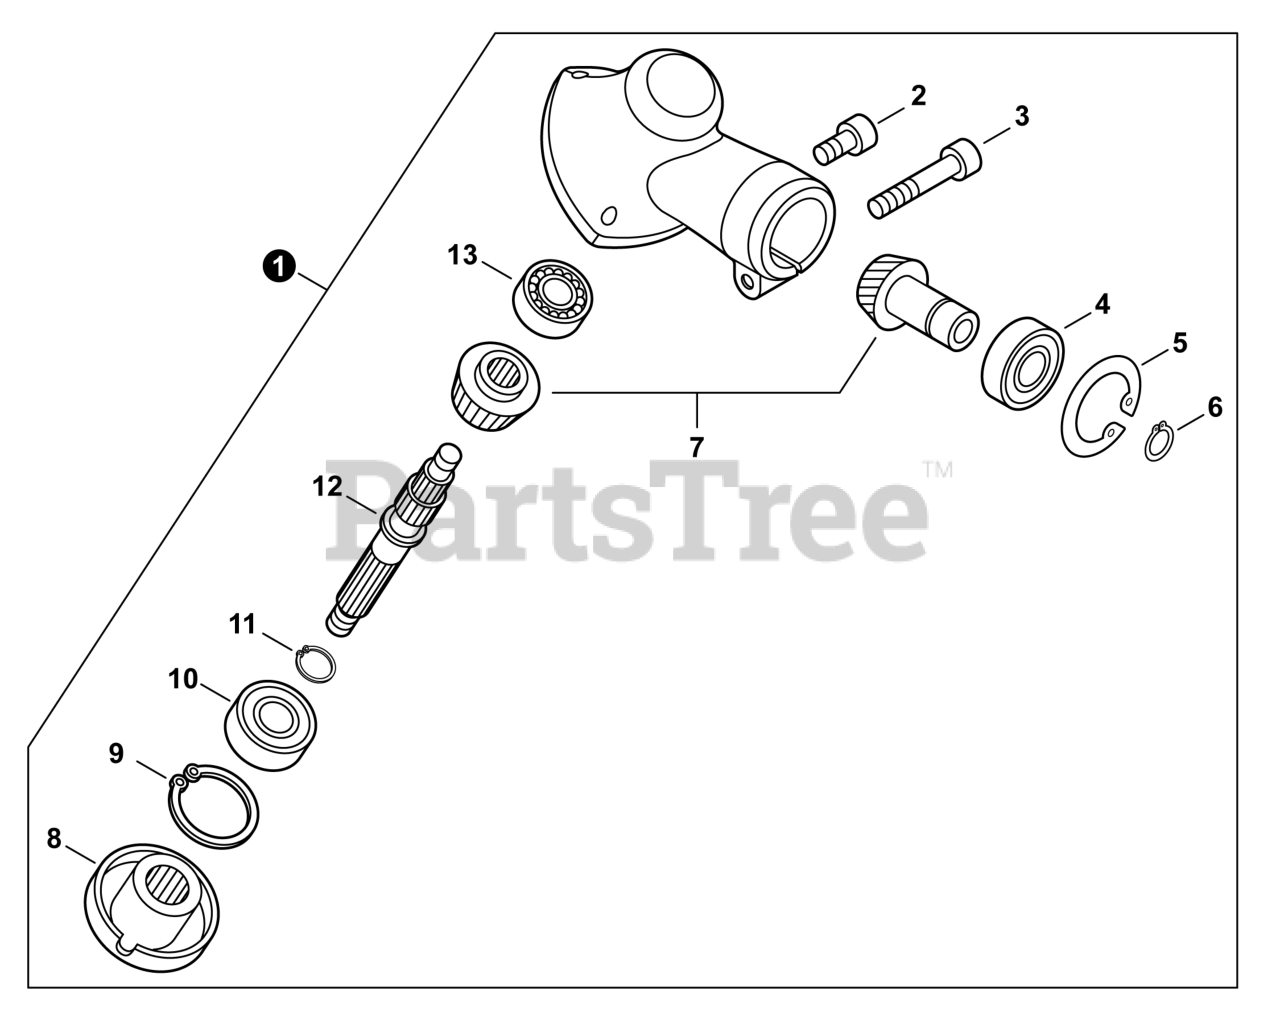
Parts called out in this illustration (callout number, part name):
1	CASE, GEAR
2	BOLT, TORX 5x10
3	BOLT, TORX 5x25
4	BEARING, BALL
5	C-CLIP 24
6	C-CLIP 9
7	GEAR SET, BEVEL
8	PLATE, ADAPTOR - UPPER
9	C-CLIP 24
10	BEARING, BALL
11	RING, SNAP
12	SHAFT, GEAR
13	BEARING, BALL
